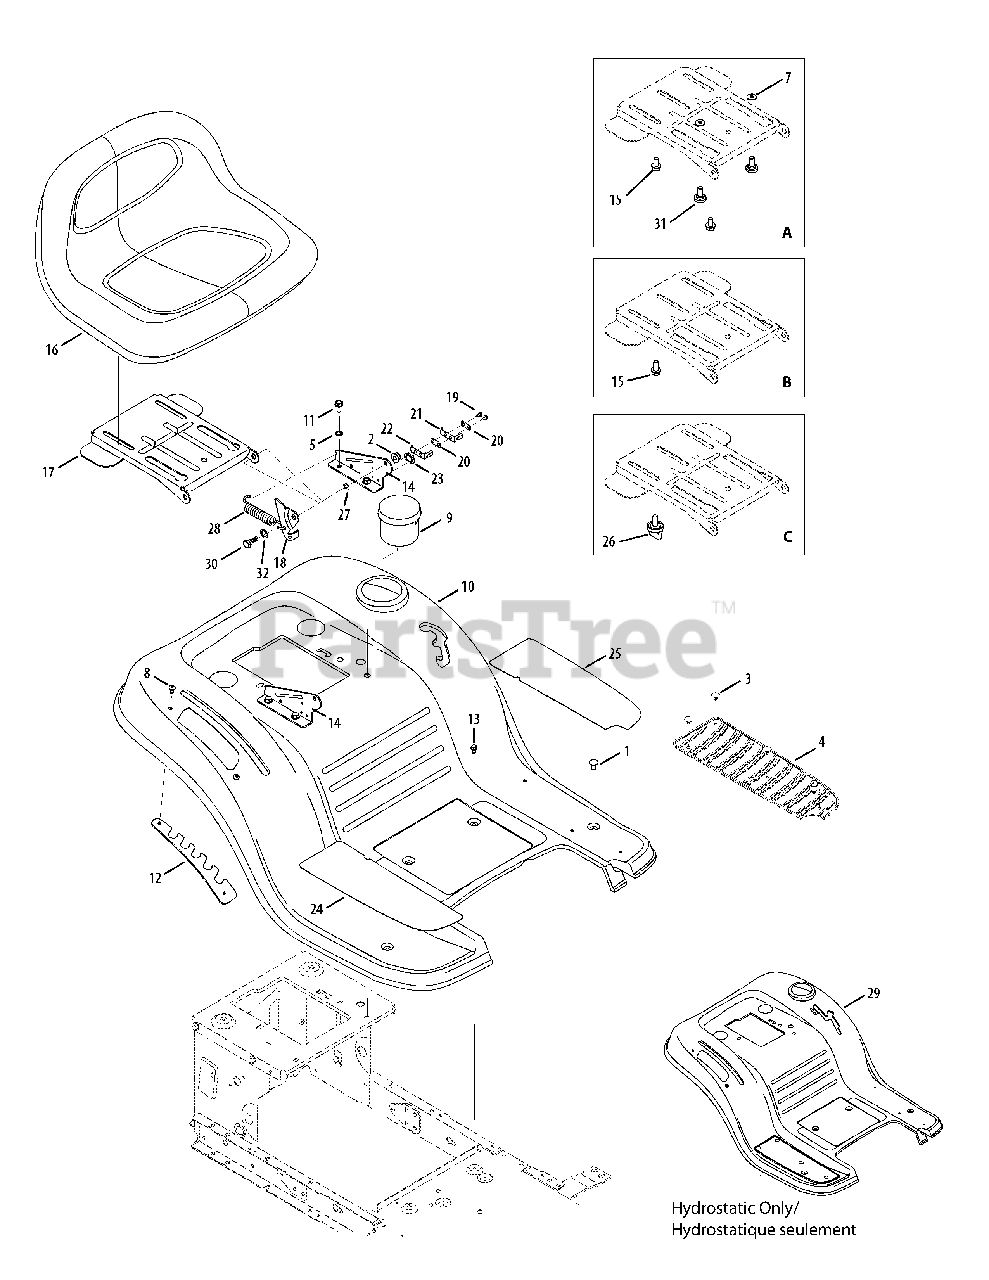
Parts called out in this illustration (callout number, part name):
1	Carriage Bolt 1/4-20 x .62
2	Flange Locknut 5/16-18 Gr. F, Nylon
3	Ratchet Clip
4	Foot Pad, RH
4	Foot Pad, LH
5	Lockwasher 5/16 ID
6	Flat Washer .510 x .750 x .033
7	Flat Washer .405 x .875 x .059
7	Flat Washer .395 x .62 x .063
8	Tap Screw 1/4-20 x .50
9	Cup Holder
10	Fender
11	S-Tapp Scr 5/16-18 x .75
12	Lift Adjustment Bracket
13	Hex Wash S-Tapp Scr 1/4-20 x .50
14	Seat Mounting Bracket
15	Screw 3/8-16 x .875
16	Seat, Low Back
17	Seat Pivot Bracket
18	Seat Lift Bracket
19	Hex Wash HD AB S-Tapp Scr #8-.50
20	Insulator Plate
21	Spring Switch
22	Seat Spring Switch
23	Insulator Plate
24	Foot Pad, Abrasive, RH
25	Foot Pad, Abrasive, LH
27	Cupp. Washer .345 ID x .88 OD x .060
28	Extension Spring .84 Dia. x 4.6
29	Fender - Hydrostatic
30	Shoulder Screw
31	Shoulder Screw .625 x .175, 3/8-16
32	Flat Washer .510 x .75 x .033
